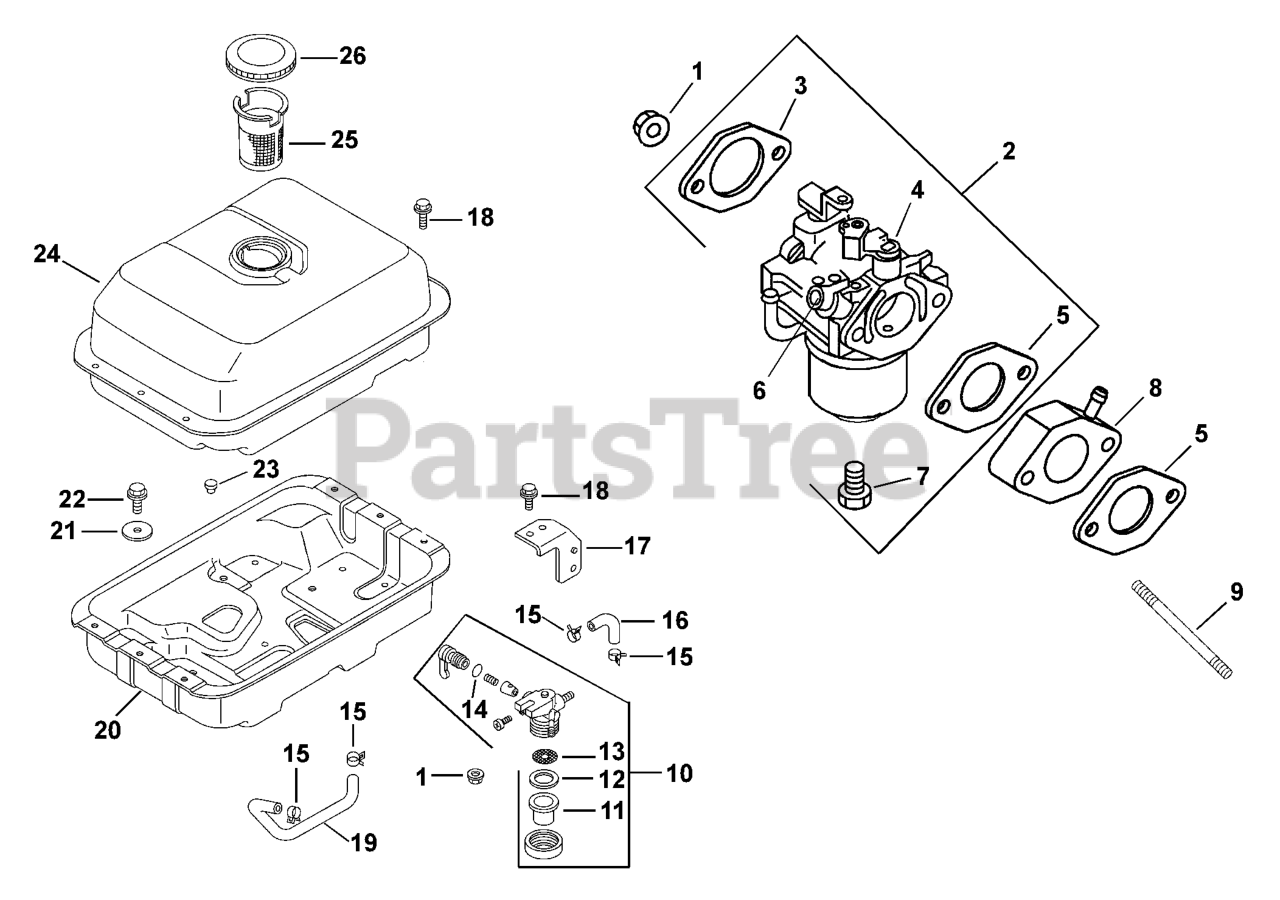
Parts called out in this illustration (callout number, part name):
2	KIT, CARBURETOR W/GASKETS
3	GASKET, A/C 8.5
4	Carburetor
5	GASKET, CARBURETOR 8.5
6	CAP, CARBURETOR ADJUSTING
7	SCREW, FLOAT BOWL CS 8
8	MANIFOLD, INTAKE CS8.5
9	STUD, CARBURETOR CS8.5
10	VALVE, FUEL SHUT-OFF CS8.5
11	CUP,FILTER CS8.5-DISCONTINUED
12	GASKET, FUEL STRAINER
13	FILTER SCREEN, CS8
14	O-RING, PETCOCK
15	CLIP CS8.5
16	FUEL LINE, CS8
17	BRACKET, FUEL VALVE, CS8.5
19	FUEL LINE, CS8.5
20	BRACKET, TANK CS8.5
21	WASHER, CS8.5
24	FUEL TANK CS8
25	STRAINER, CS8.5
26	CAP, FUEL TANK
